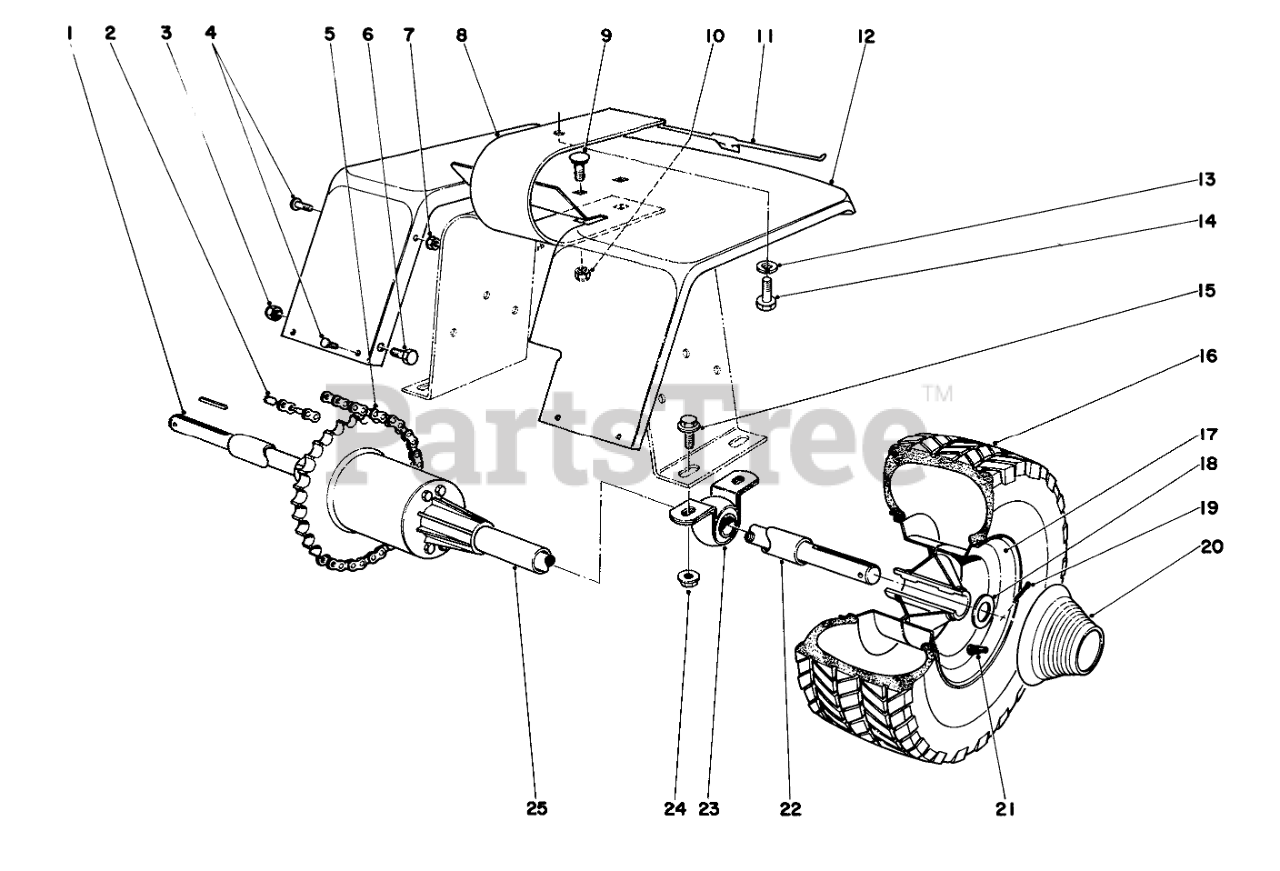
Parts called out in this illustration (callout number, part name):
1	Differential
2	LINK-CONNECTING
3	NUT-LOCK, CONE
4	10-24 X 3/8 PAN HD SC
5	Roller Chain
6	SCREW-HH
7	NUT-KEPS
8	Seat Spring
9	BOLT-CARR
10	NUT-LOCK, CONE
11	Decal
12	Fender
13	WASHER-LOCK
14	Capscrew
15	SCREW-HHF
16	Tire
18	Waxer
19	PIN-COTTER
20	Hub Cap
21	STEM-VALVE
22	Tube Rear Axle
23	PILLOW BLOCK
24	NUT-HF
25	Tube Rear Axle
